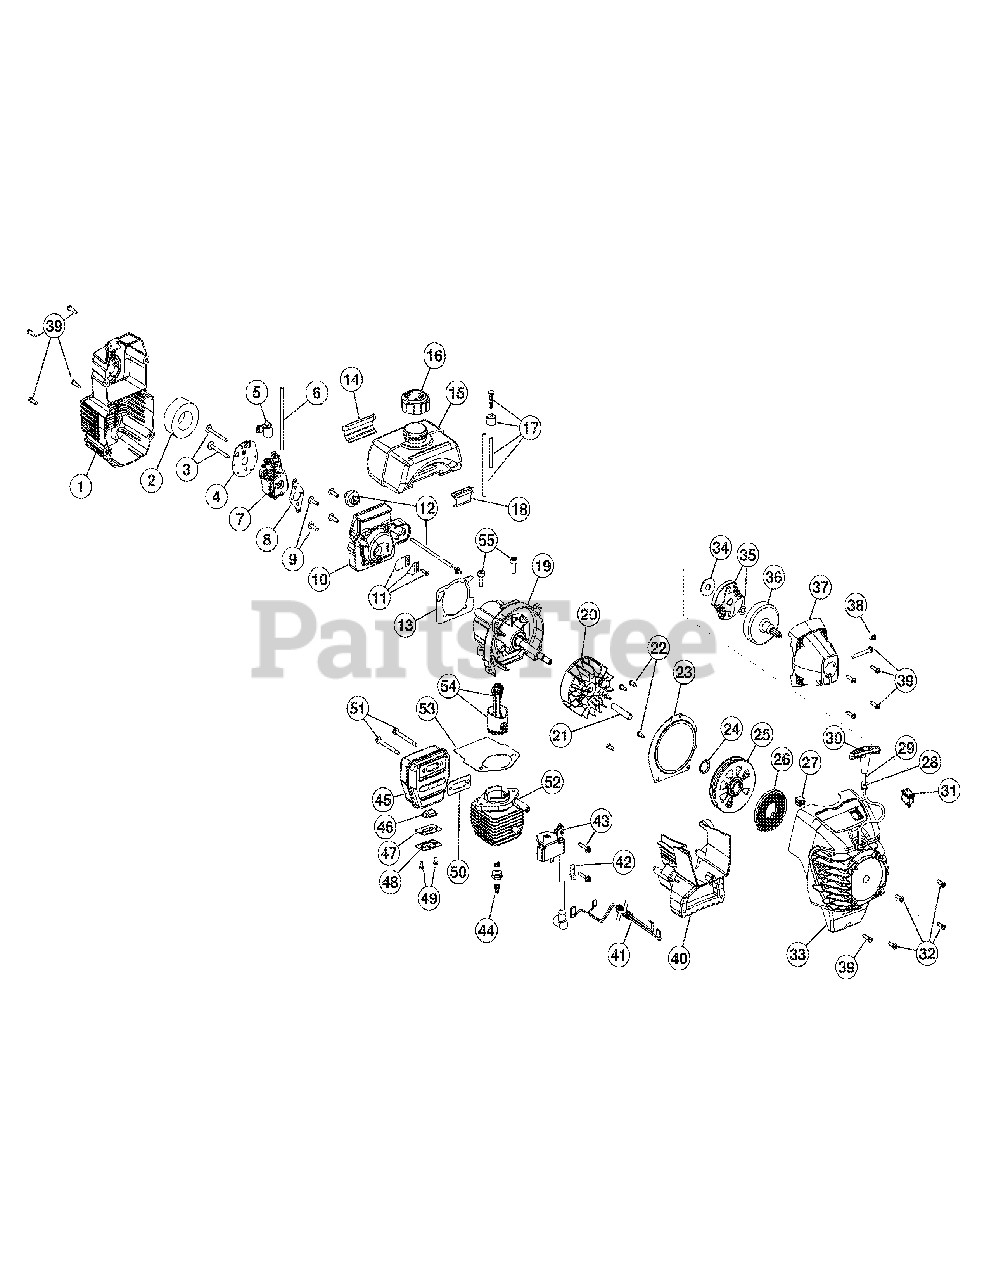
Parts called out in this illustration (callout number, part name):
1	Air Cleaner Cover Assembly (includes 2 and 39)
2	Air Cleaner Filter
3	Carburetor Mounting Screw Assembly
5	Choke Plate
5	Choke Lever
6	Fuel Return Line
7	Carburetor Assembly (includes 8 and 17)
8	Carburetor Gasket
9	Carb Mount Screw
10	Carb Mount Assembly (includes 9, 11 and 13)
11	Reed Assembly
12	Primer and Hose Assembly
13	Carburetor Mount Gasket
14	Rear Mounting Pad
15	Fuel Tank Assembly (includes 6, 16 and 17)
16	Fuel Cap Assembly
17	Fuel Line Assembly
18	Front Mounting Pad
19	Crank Case Service Assembly (includes 9)
20	Flywheel Assembly
22	Pressure Plate Screw
23	Pressure Plate
24	Pulley Retainer
25	Recoil Pulley Assembly
26	Recoil Spring
27	Rope Guide Retainer
28	Rope Guide
30	Pull Handle
32	Housing Screw
33	Starter Housing Assembly (includes 22-32 and 39)
34	Clutch Washer
35	Clutch Rotor Assembly
36	Clutch Drum Assembly
37	Clutch Cover Assembly (includes 38 & 39)
38	Anti-Rotation Screw
39	Cover Screw
40	Shroud Extension & Stand (includes 39)
41	Wire Leads and Sleeve
42	Ground Tab
43	Module Assembly
44	Spark Plug
45	Muffler Assembly (includes 46-51)
46	Spark Arrestor Screen
47	Spark Arrestor Plate
48	Spark Arrestor Hood
49	Spark Arrestor Screw
50	Exhaust Gasket
51	Muffler Mounting Bolt Assembly
52	Cylinder Assembly (includes 53 & 54)
53	Cylinder Gasket
54	Piston and Rod Assembly
55	Cylinder Bolt
